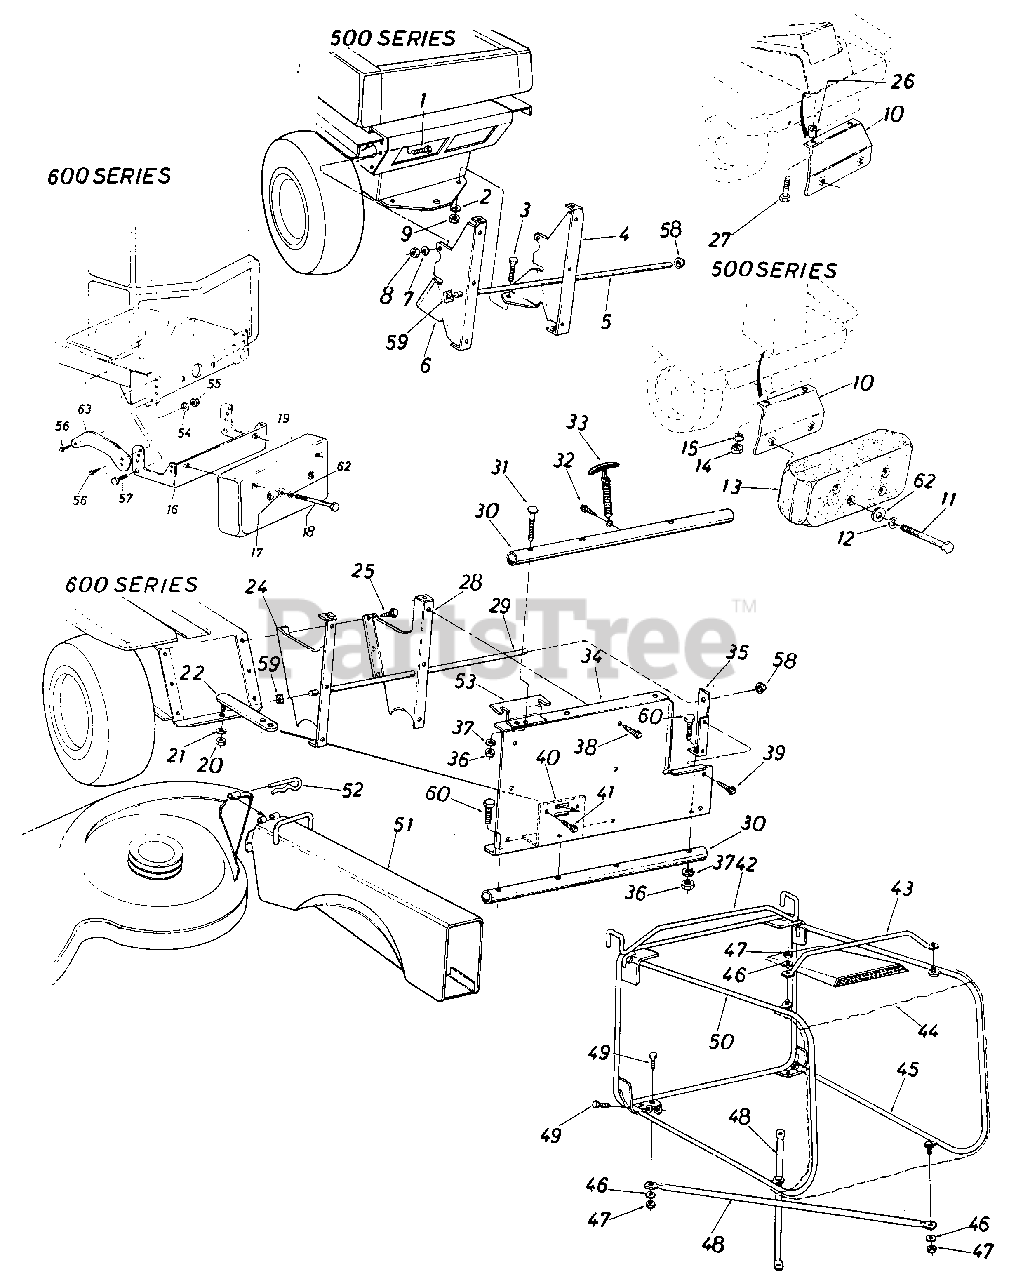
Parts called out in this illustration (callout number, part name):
1	SCREW-HEX 5/16-18 X 1.00
2	WASHER-LOCK-5/16
3	SCREW-HEX 5/16-18 X 1.00
4	BRACKET-SUPPORT-RH
7	WASHER-LOCK-5/16
8	NUT-HEX 5/16-18
9	NUT-HEX 5/16-18
10	BRACKET-SUPPORT
11	SCREW-HEX 3/8 X 4.5 N.C GR. 5
12	WASHER-BELL .400 ID X .88 X .060
13	COUNTERWEIGHT
14	NUT-HEX 5/16-18
15	WASHER-LOCK-5/16
16	BRACKET-WEIGHT
17	WASHER-BELL .400 ID X .88 X .060
18	SCREW-HEX 3/8 X 4.5 N.C GR. 5
19	COUNTERWEIGHT
20	NUT-HEX JAM 1/2-20
21	WASHER-LOCK-1/2
25	SCREW-HEX HD TAP
28	BRACKET-SUPPORT-RH
31	BOLT-CARRIAGE 5/16-18 X 1.75
32	SCREW-HEX WASH HD
33	LOCK ASSY-HOOD
34	ADAPTER-GRASSCATCHER
35	BRACKET-SUPPORT-RH
36	NUT-HEX 5/16-18
37	WASHER-LOCK-5/16
38	SCREW-HEX WASH SF TAPP
39	SCREW-HEX WASH SF TAPP
40	BRACKET-HITCH
41	SCREW-HEX WASH SF TAPP
42	FRAME-CATCHER
43	HANDLE-CATCHER
44	BAG-GRASS
47	NUT-HEX CENTER L-1/4-20
48	BRACE-CROSS-BOTTOM
49	SCREW-HEX 1/4-20 C .62
53	PLATE-SUPPORT
54	WASHER-LOCK-7/16
55	NUT-JAM 7/16-20
56	SCREW-HEX AB-TAP
57	SCREW-HEX 7/16-20 X 1.00
59	NUT-PUSH-SPEED .50 DIA
60	SCREW-HEX 5/16-18 X 1.75
62	WASHER-FL
63	TIE-STRAP
